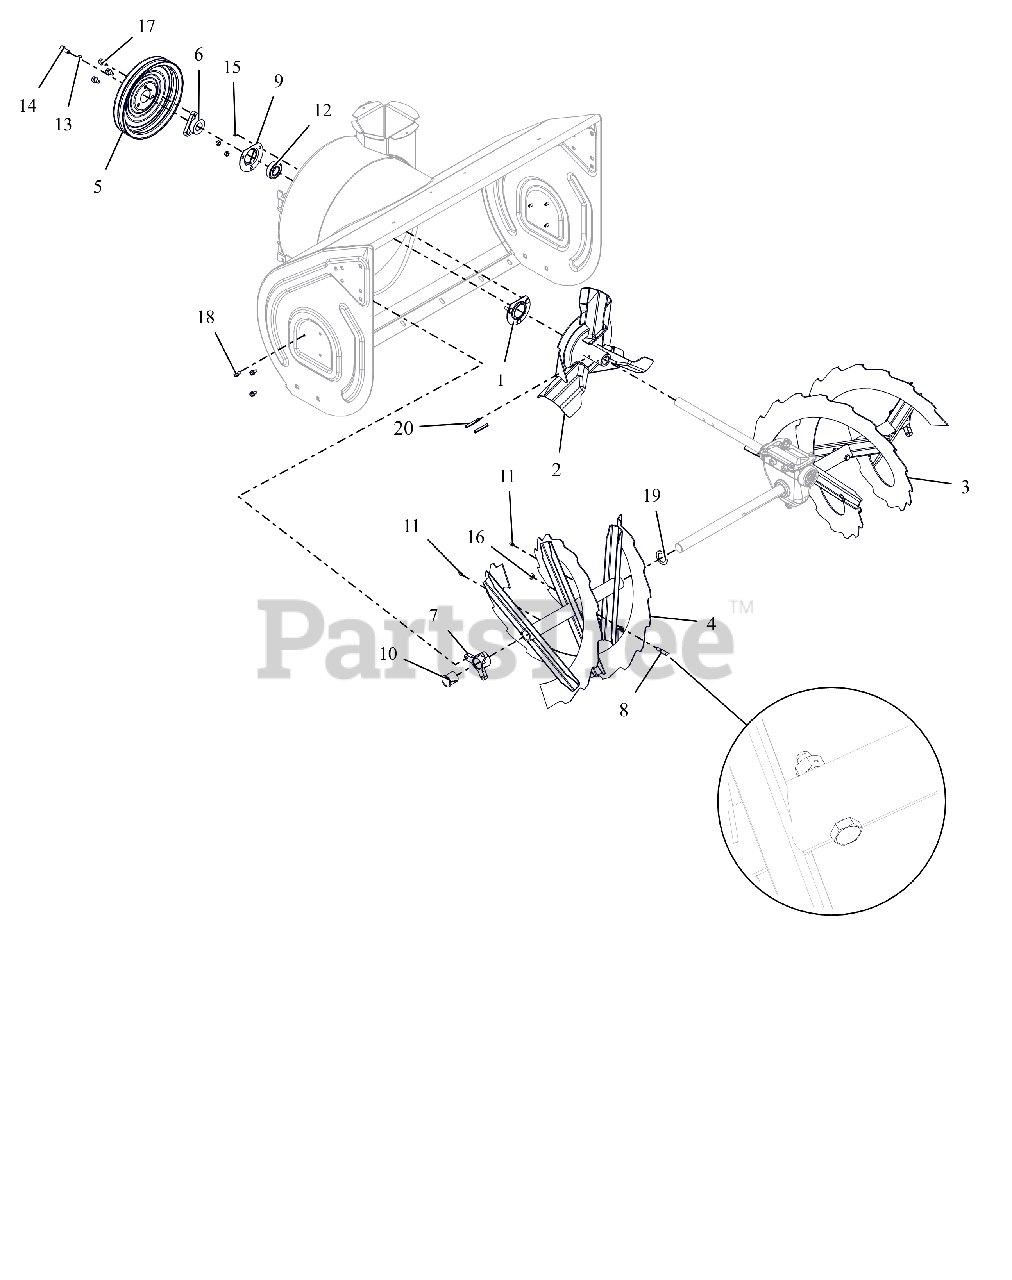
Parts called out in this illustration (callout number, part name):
1	BEARING FLANGE
2	IMPELLER, 3 BLADE-14"
3	RAKE, LH-32"(1 ID X 15.75 OD)
4	RAKE, RH-32"(1 ID X 15.75 OD)
5	PULLEY, SPIN FORM DUAL GROOVE
6	PULLEY HUB, D-BORE .87 PRO
7	BUSHING, RAKE SHAFT 1"
8	SHEAR BOLT SERVICE ASSEMBLY
9	BEARING FLANGE
10	BSHG-FLG SPLIT NYLINER 1.0" HP
11	ZERK,FITTING .25X.125 DRIVE IN
12	BRG-BALL .876X1.75X.50 RSTFP
13	WSHR, LK-HVY .312X.097 ZCC
14	BLT, HEX .31-24X.750 G5 ZCC
15	NUT,LK-CTR .25-20 GA ZCC
16	NUT,LK-CTR .31-18 GA ZCC
17	SCR,TAP .312-18X.50 HWH TR ZCC
18	SCR-TAP .25-20X.50 HWH ZCC
19	WSHR, FLT 1.010X1.505X.062 ZCC
20	PIN-ROLL .250X1.75
